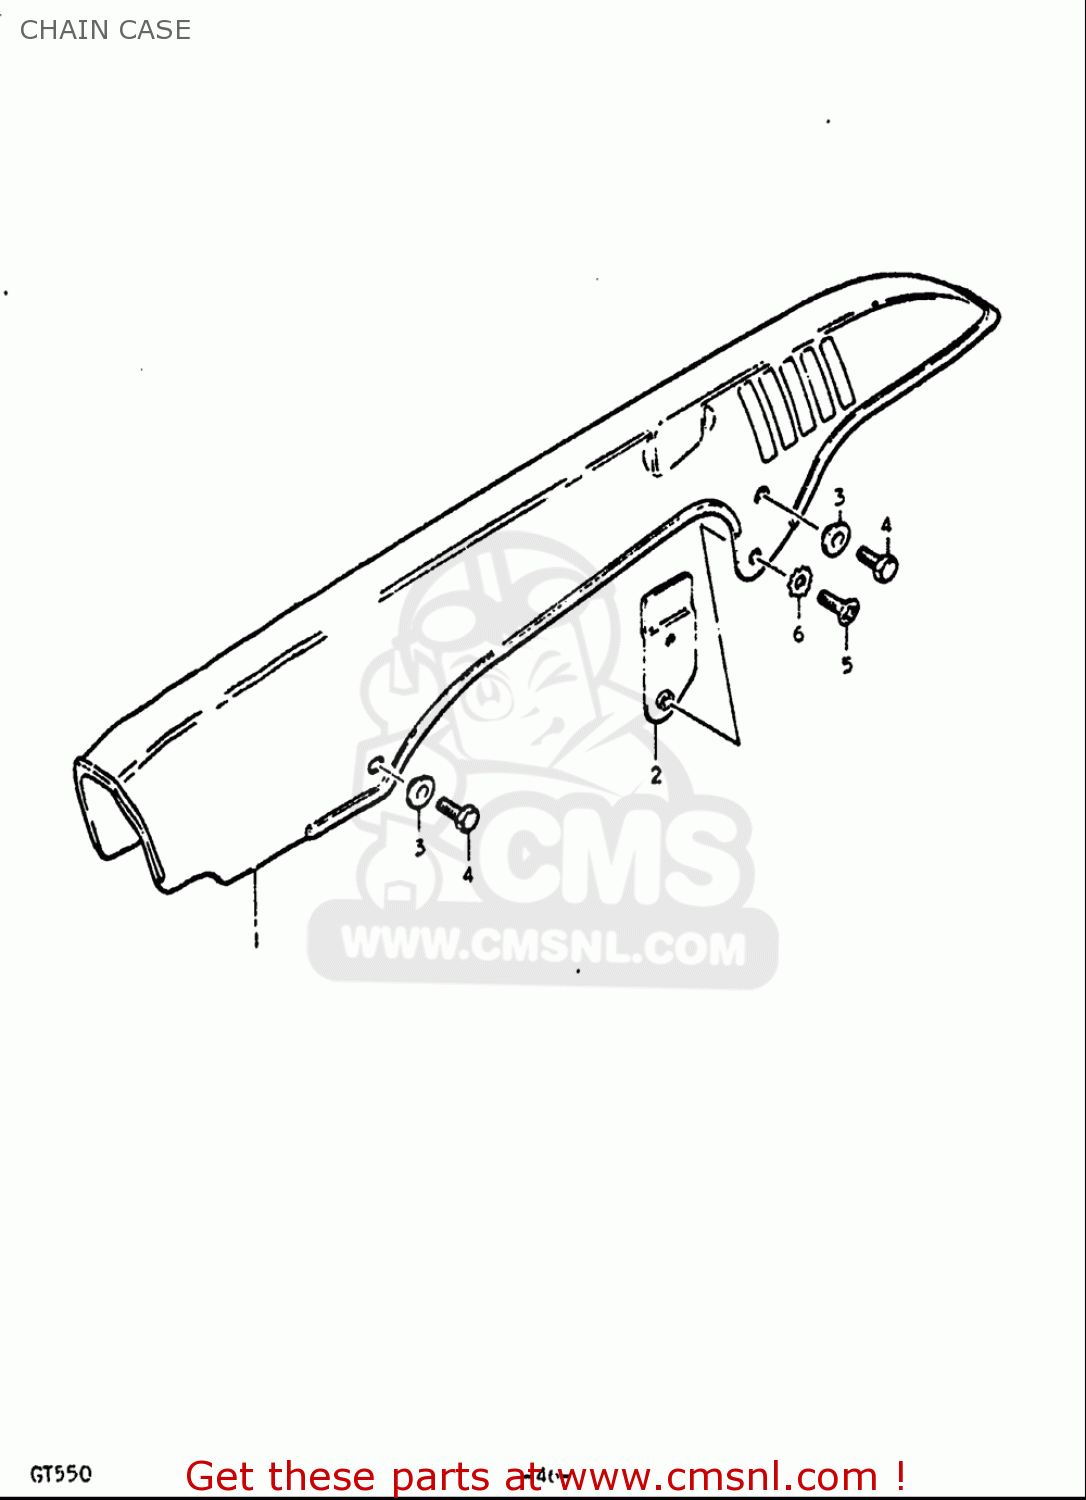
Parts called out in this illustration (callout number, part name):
3	WASHER
4	BOLT(6X8)
5	SCREW
6	LOCK WASHER
